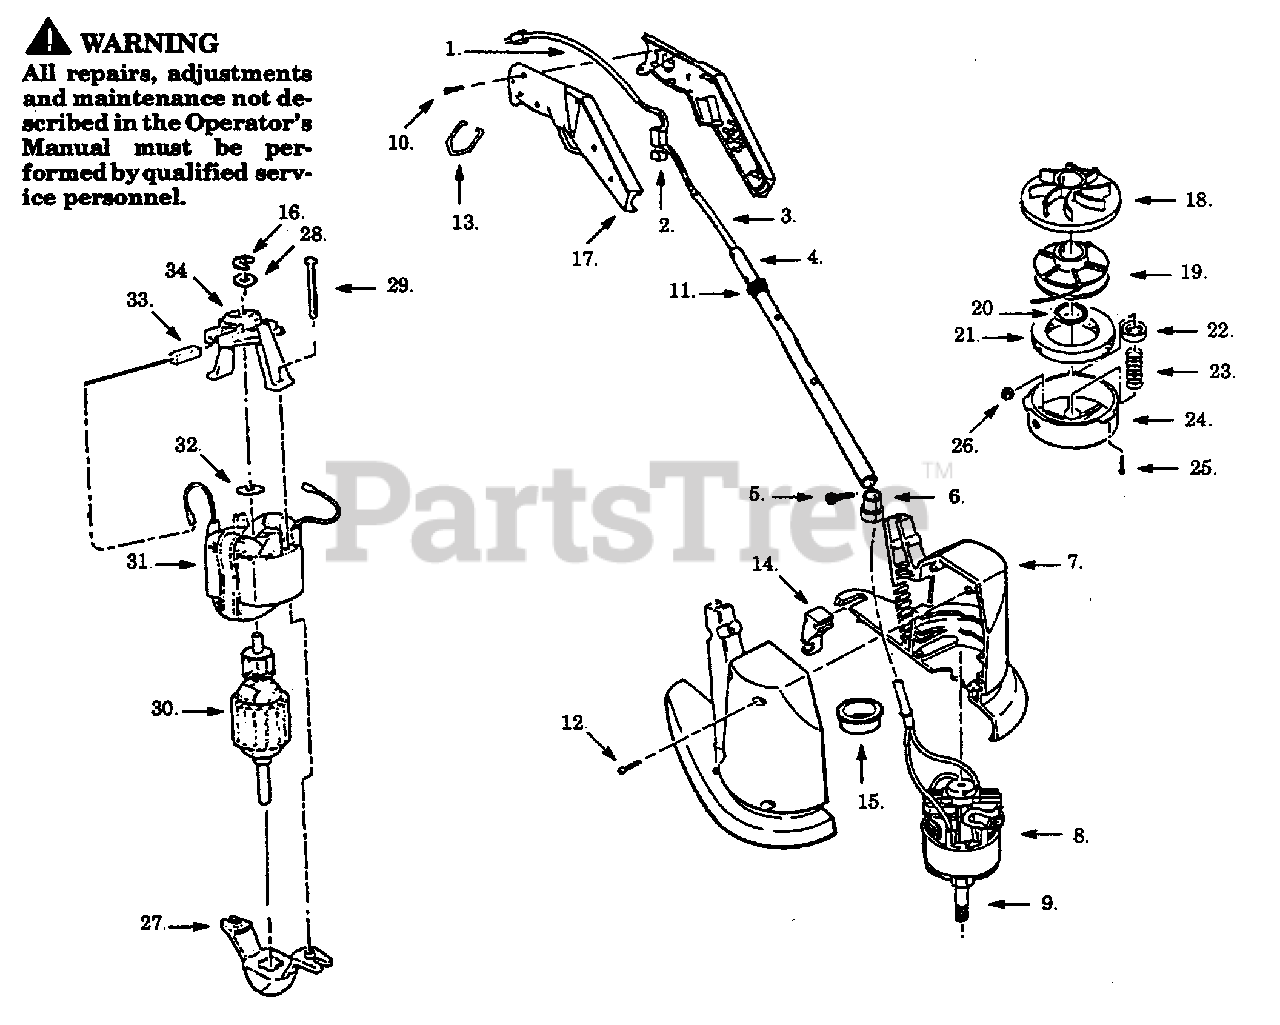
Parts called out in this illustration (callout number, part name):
1	Power Cord
2	Trigger Switch
6	Rain Guard
7	R.H./L.H. Housing
9	Drive Adapter
14	Blade Retainer
15	Air Baffle
16	Retaining Ring
17	R.H./L.H. Handle
18	Rear Plate
19	Spool & Line
21	Foam Pad
22	Adapter Nut
24	Hub Ass'y.
25	Cotter Pin
27	Endbell Ass'y. (Drive)
30	Armature Ass'y.
31	Field Ass'y.
34	Endbell Ass'y. (Brush)
